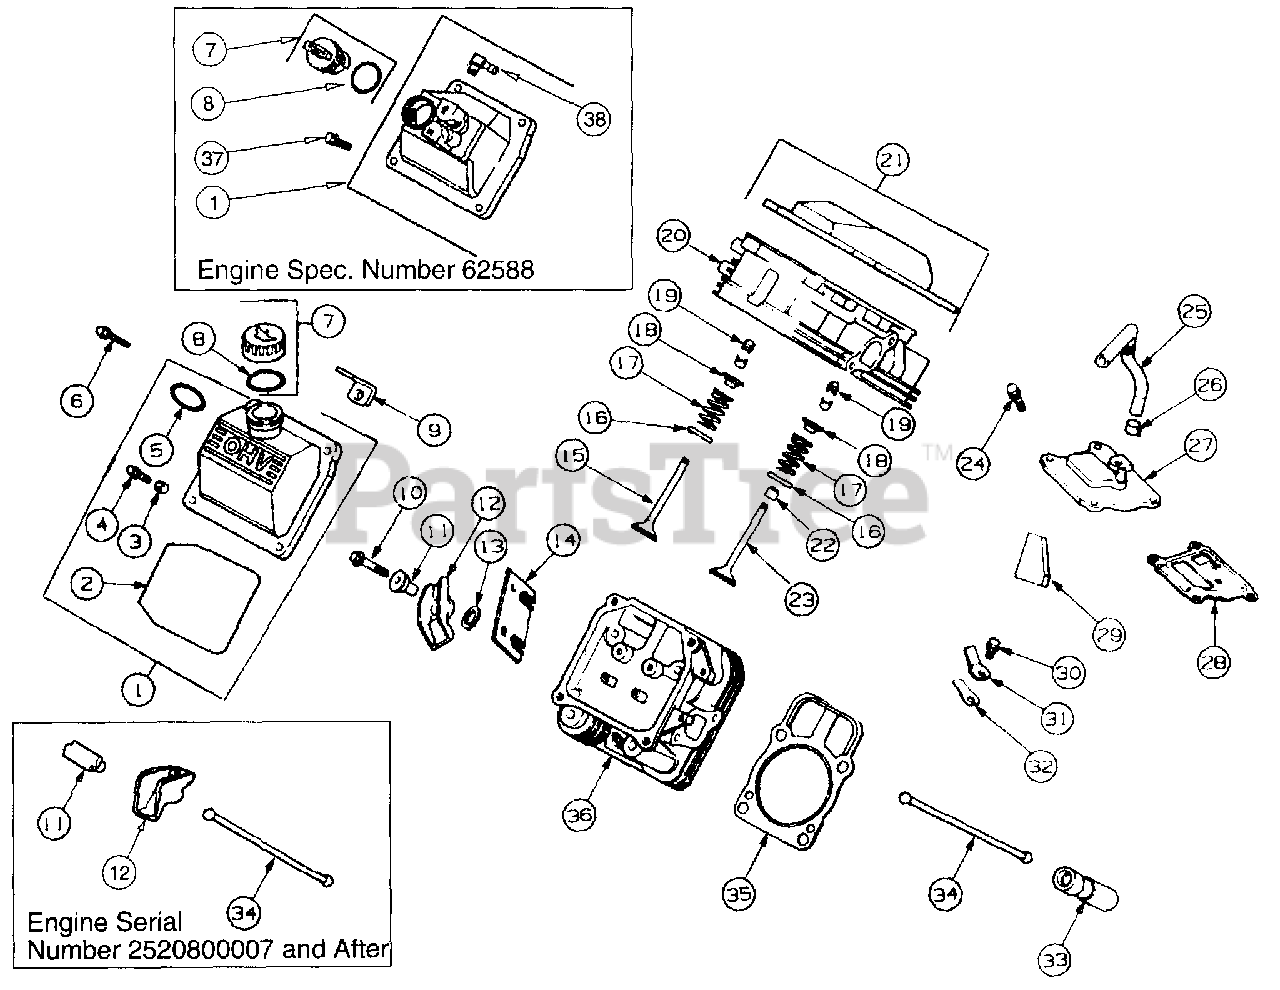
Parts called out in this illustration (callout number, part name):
1	Kit, Valve Cvr
2	O-Ring, Cover
4	Screw, M6 x 1.0 x 30
5	O-Ring, Filler Neck
6	Screw, M10 x 1.5 x 91
7	Kit, Oil Cap
8	O-Ring
9	Strap, Lifting
10	Screw, M6 x 1.0 x 34
11	Pivot, Rocker Arm
12	Arm, Rocker
13	Washer, Flat
14	Plate, Guide
15	Valve, Exhaust, Std
16	Retainer, Spring
17	Spring, Valve
18	Cap, Valve Spring
19	Lock, Retainer
20	Head Assy, Cylinder #1
21	Kit, Valve Covr
22	Seal, Valve Stem
23	Valve, Intake, Std
24	Screw, M6 x 1.0 x 20
25	Hose, Breather
26	Clamp, Hose
27	Cover, Breather
28	Gasket, Breather
29	Filter, Breather
30	Screw, Reed Retainer M5 x 0.8 x 10
31	Retainer, Breather Reed
32	Reed, Breather
33	Lifter, Valve
34	Rod, Push
35	Gasket, Cylinder Head
36	Head Assy, Cylinder #2
37	Screw, Shlder
38	Connector 90°.
